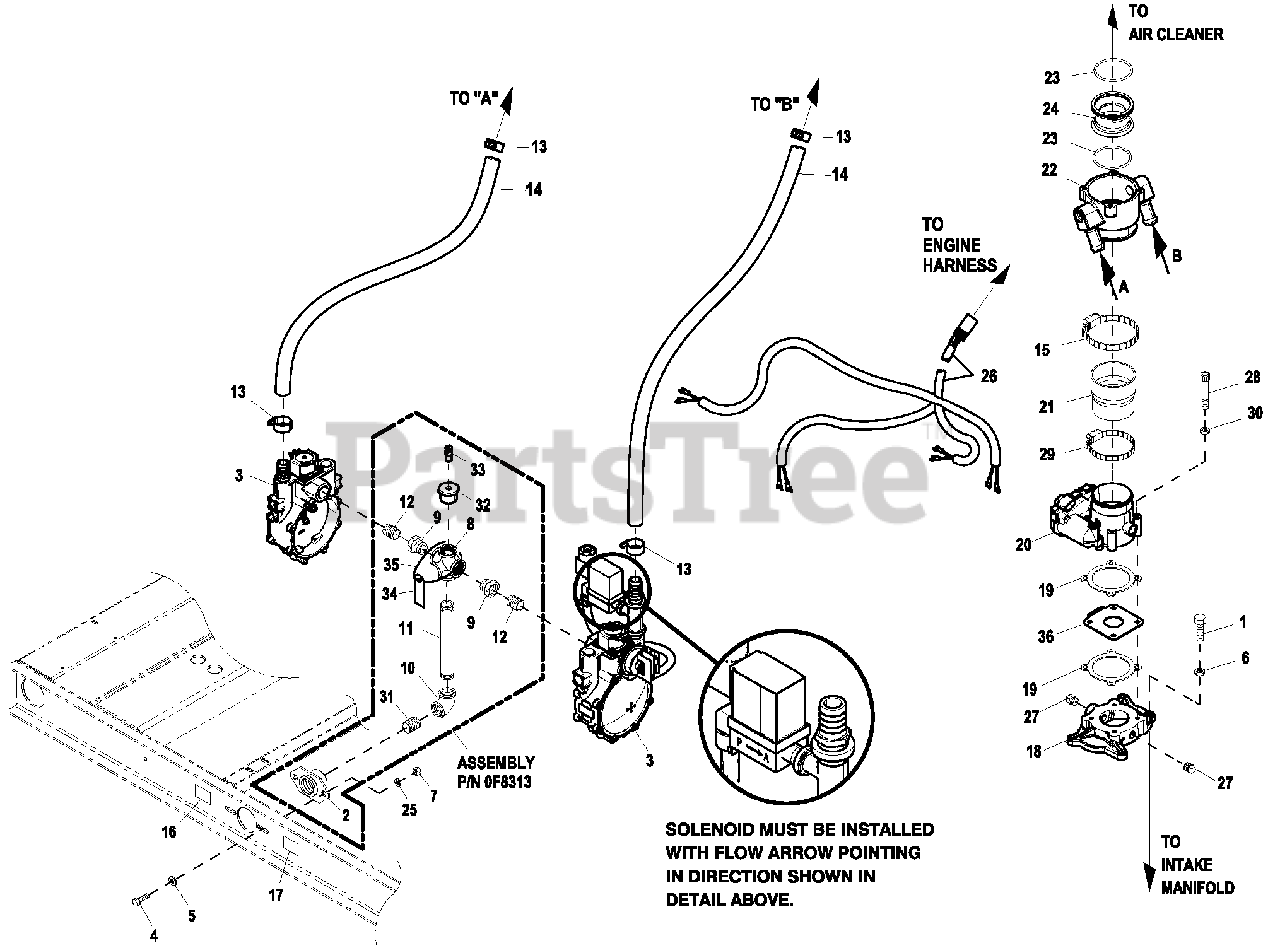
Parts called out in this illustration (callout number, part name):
1	SCREW HHC 5/16-18 X 1-1/4 G5
2	SUPPORT NAT GAS SOLENOID
3	REG ASSY5.4L 80 KW LP CPL
4	SCREW HHC M12-1.75 X 20 G8.8
5	WASHER FLAT 1/2 ZINC
6	WASHER LOCK M8-5/16
7	NUT HEX M12-1.75 G8 YELCHR
8	PIPE CROSS 1-1/4" NPT
9	BSHG RDCR HEX 1-1/4-3/4
10	ELBOW 90D 1-1/4 NPT
11	NIPPLE PIPE 1-1/4 NPT X 3
12	NIPPLE CLOSE 3/4X1.375
13	CLAMP HOSE #10.56-1.06
14	HOSE 3/4 ID SAE-30R2 (45" LG)
15	CLAMP HOSE #52 2.81-3.75
16	DECAL INLET PRESSURE
17	DECAL FUEL INLET LPG
18	MACHINING, INTA KE ADAPTOR 60MM
19	GASKET GOVERNOR ACTUATOR
20	ACTUATOR BOSCH 60 GOVERNOR
21	REDUCER 3.0" TO 2.75" TURBO
22	MIXER 40/60MM ACTUATOR ASSY
23	O-RING 2-3/4X3/32X2-15/16
24	VENTURI, THROTTLE 38MM
25	WASHER LOCK 1/2
26	HARN FUEL JUMPER DUAL REG
27	PLUG STD PIPE 1/4 STEEL SQ HD
28	SCREW SHC M6-1.0X50 C8.8
29	CLAMP HOSE #442.31-3.25
30	WASHER LOCK M6-1/4
31	NIPPLE CLOSE 1.25 NPT X 1.625
32	BSHG RDCR HEX 1-1/4 X 1/4FNPT
33	PLUG, PRESSURE GAUGE, 1/4" NPT
34	HANG TAG FUEL PRESS TEST POINT
35	TIE WRAP UL 5.6 X.10BLAC K
36	RESTRICTOR INTA KE 4.6L G3 LPV
